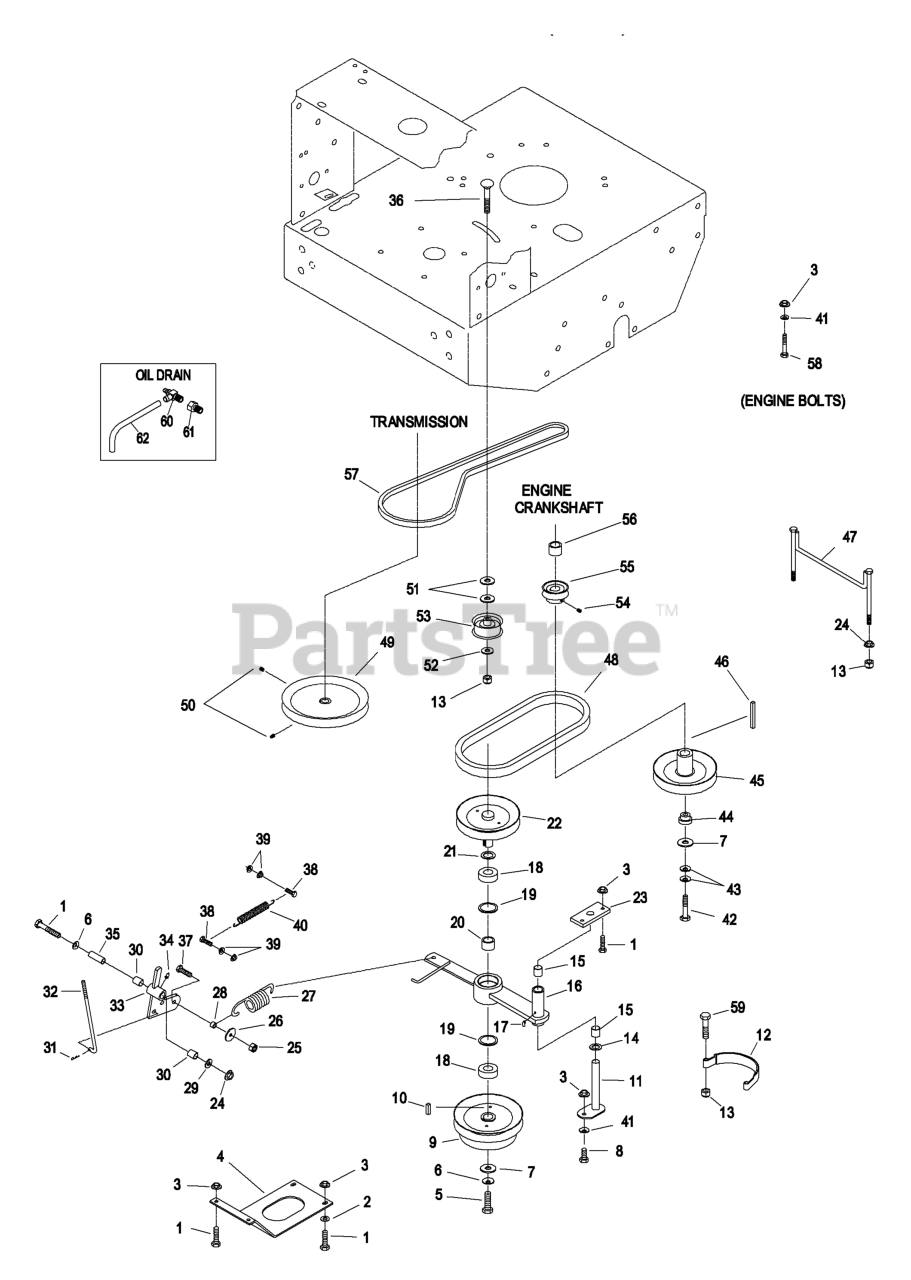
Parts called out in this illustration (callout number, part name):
1	SCREW-HH
2	WASHER-FLAT
4	PLATE-GUARD
5	SCRW,CAP HH
6	WASHER-BELLEVILLE
8	SCREW-HH
9	SHEAVE,6.13 W/HUB
11	WLD,PIN PIVOT
12	BAND,BRAKE BLADE
13	NUT-LOCK, NI
14	WASHER-SPACER
15	SLEEVE,BEARING
16	Arm Weldment, Clutch
17	FITTING-GREASE
18	BEARING,CLUTCH SHAFT
19	RING-SNAP
20	SPACER,CLUTCH BEARING
21	WASHER-SPACER
22	SHEAVE,6.13 W/SHAFT
23	PLATE-CLUTCH PIVOT
24	NUT-HHF, WHIZ
25	NUT-LOCK, NI
27	SPRING,BELT TENSION
28	SPACER,CLUTCH ANCHOR
29	WASHER-FLAT
30	SLEEVE-BEARING
31	PIN-COTTER
32	LINKAGE,LOWER
33	ASM,PIVOT W/BUSHINGS
34	FITTING-GREASE
35	BUSHING
36	SCREW-HH
37	SCREW-HH
38	SCREW-HH
40	SPRING,EXTENSION
41	WASHER-SPRING
42	SCREW-HH
43	WASHER-SPRING
44	BUSHING,CLUTCH KEEPER
45	SHEAVE,ENGINE
46	KEY,MACH 1/4X1/4X2-5/8
47	GUIDE - BELT
48	BELT,BLADE CLUTCH
49	SHEAVE-TRANSMISSION
50	SCREW-HSH
51	WASHER-FLAT
52	WASHER-FLAT
54	SCREW-SET
55	SHEAVE-TRANSMISSION
56	SPACER,CRANKSHAFT
57	BELT,TRANS DRIVE
58	SCREW-HH
59	SCREW-HH
60	VALVE-DRAIN, OIL
61	ADAPTER
62	HOSE-DRAIN, OIL
